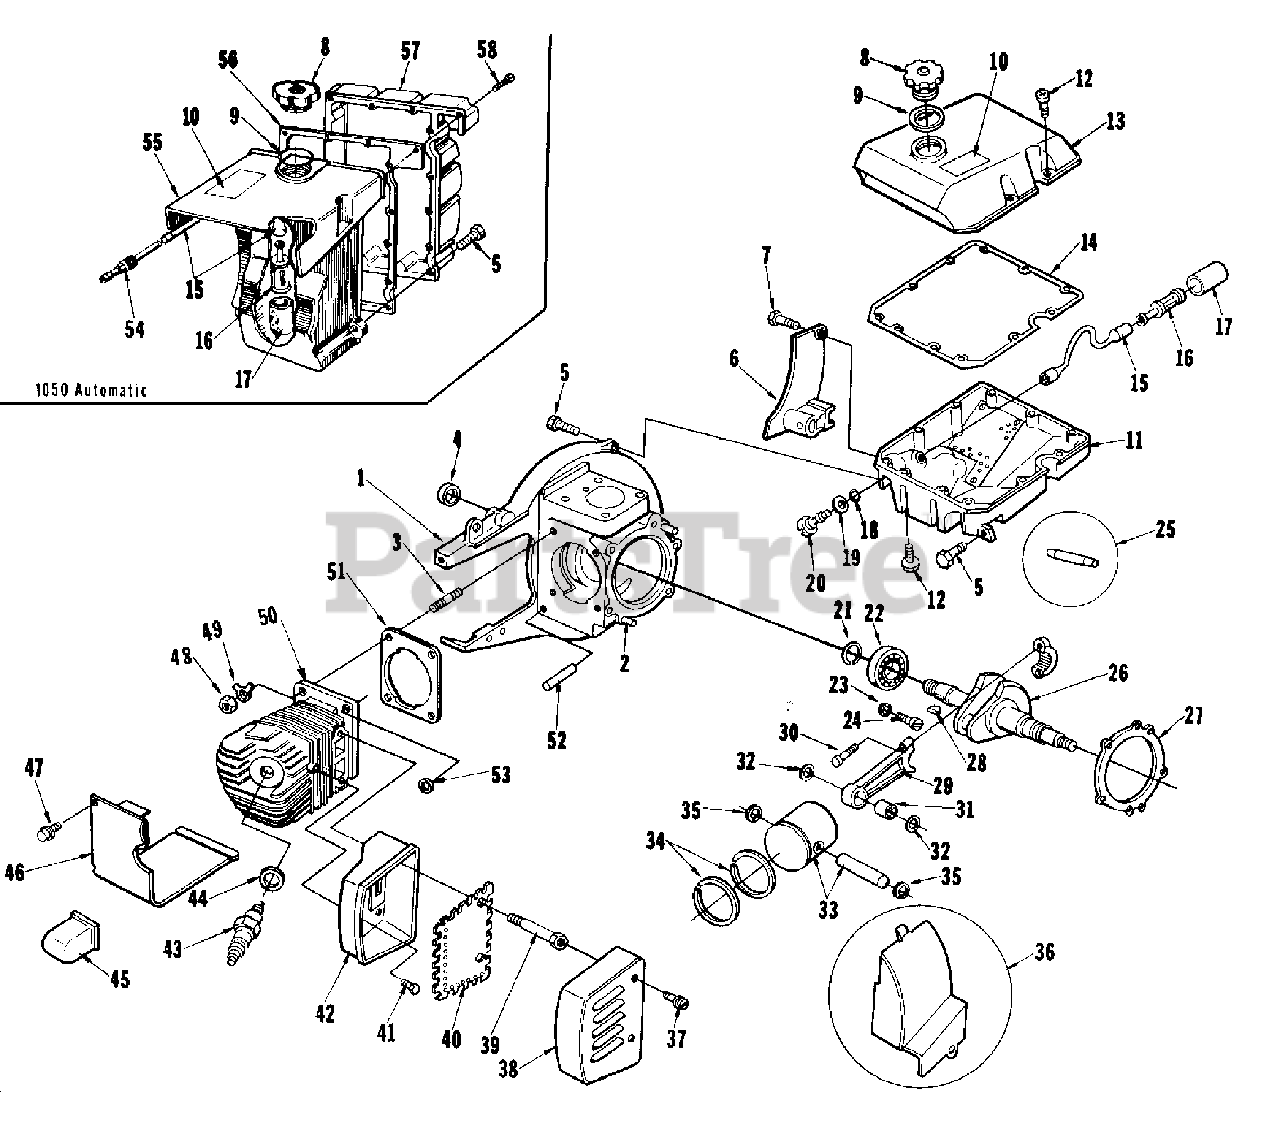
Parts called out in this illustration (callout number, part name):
1	CRANKCASE- W/pins
2	PIN- Dowel
4	SEAL
5	SCREW- Hex, 12-24 x 3/4
8	CAP- Fuel tank
10	LABEL- Warning
15	FLEXIBLE LINE
16	FILTER ASSEMBLY
17	FILTER
21	RING- Retaining
22	BEARING- Ball
23	WASHER- Lock
24	SCREW- Bearing retaining
25	ROLLERS- Set of 31
26	CRANKSHAFT
28	KEY- Woodruff
29	CONNECTING ROD
30	SCREW- 10-32 x 5/8
31	BEARING- Needle
32	WASHER- Thrust
33	PISTON & PIN
34	PISTON RING
35	RING- Retaining
36	EXCHANGER- Heat (optional)
37	SCREW- Hex, 12-24 x 3/8
38	CAP- Muffler
39	STUD- Muffler
40	BAFFLE- Muffler
41	SCREW- Hex, 1/4-20 x 5/8
42	BODY- Muffler
43	SPARK PLUG
45	CAP- Spark plug
46	CYLINDER SHIELD
47	SCREW- Hex , 10-24 x 3/8
48	NUT- Hex 5/16-24
49	WASHER- Lock
50	CYLINDER
52	SLEEVE- Insulating
53	WASHER- Lock, 5/16
54	FITTING- Fuel outlet
55	TANK- fuel
56	GASKET- Fuel tank cover
57	COVER- Fuel tank
58	SCREW- Rd., 6 x 1/2
